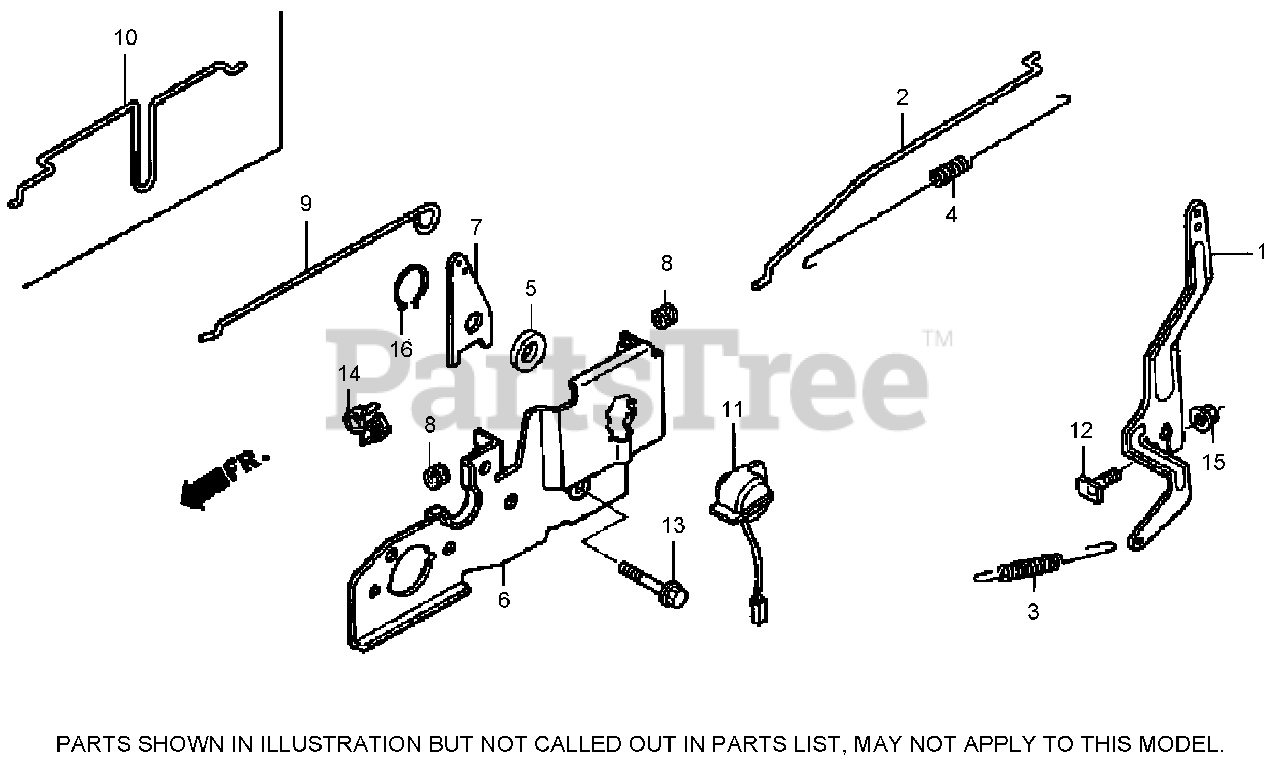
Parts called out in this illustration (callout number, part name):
1	ARM, GOVERNOR
2	ROD, GOVERNOR
3	SPRING, GOVERNOR
4	SPRING, THROTTLE RETURN
6	BASE, CONTROL
12	BOLT-GOVERNOR ARM
13	BOLT, FLANGE (6X45)
15	NUT-FLANGE (6MM)
